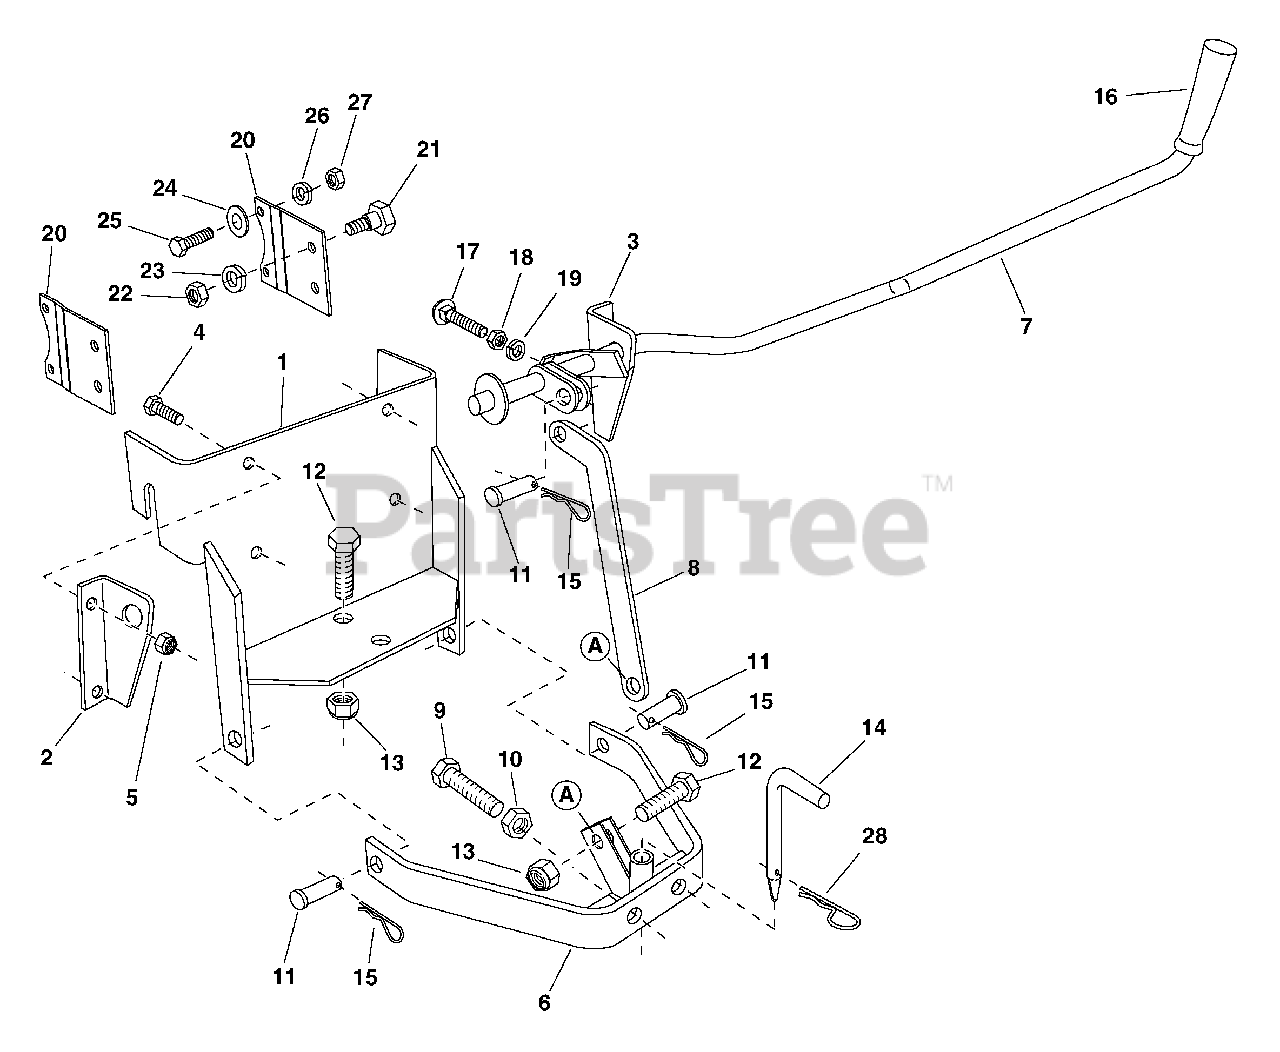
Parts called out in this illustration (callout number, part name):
1	Sleeve Hitch Frame
2	Pivot Bracket, L.H.
3	Pivot Bracket, R.H.
4	Bolt, Hex 3/8-16 x 1"
5	Nylock Nut, 3/8-16
6	Sleeve Hitch Lift Assembly
7	Lift Lever Assembly
8	Lifting Link Plate
9	Bolt, Hex 5/8-11 x 2"
10	Hex Jam Nut, 5/8-11
11	Clevis Pin, 5/8" x 1-3/4"
12	Bolt, Hex 5/8-11 x 1-3/4"
13	Nylock Nut, 5/8-11
14	Pin, Sleeve Hitch
15	Pin, Hair Cotter 3/32"
16	Grip, Plastic
17	Carriage Bolt, 5/16-18 x 1-3/4"
18	Hex Nut, 5/16-18
19	Lock Washer, 5/16"
20	Mounting Bracket
21	Bolt, Shoulder
22	Hex Nut, 1/2-20
23	Lock Washer, 1/2"
24	Flat Washer
25	Bolt, Hex 3/8-16 x 1-1/4"
26	Lock Washer, 3/8"
27	Hex Nut, 3/8-16
28	Pin, Hair Cotter, 5/32"
